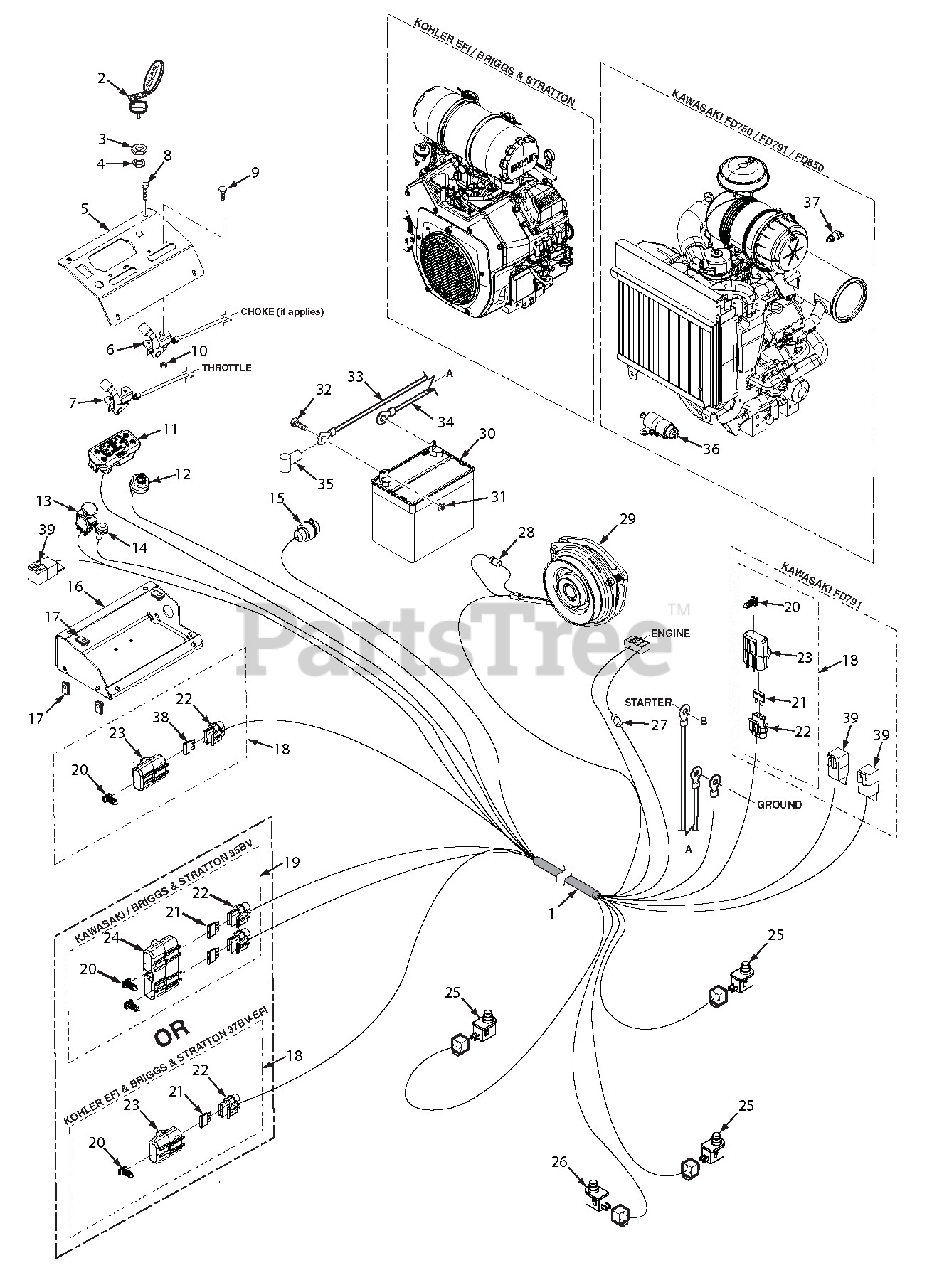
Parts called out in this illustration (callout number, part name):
1	Wire Harness, STTII-BV (Briggs & Stratton)
1	Wire Harness, STTII-BV-EFI (Briggs & Stratton)
1	Wire Harness, STTII-EFI (Kohler)
1	Wire Harness, STTII-KA (Kawasaki)
1	Wire Harness, STTII-FD791 DFI (Kawasaki)
1	Wire Harness, STTII-FD850D DFI (Kawasaki)
2	Key Assy., w/Fob
3	Nut, Hex 5/8-32
4	Lockwasher, 5/8 Internal
5	Instrument Panel w/Decal
6	Choke Cable (FD750 & 35BV)
7	Control Cable, Throttle
7	Control Cable, Throttle (35BV)
8	Capscrew, 1/4-20 x 3/4"
9	Bolt, Carriage 1/4-20 x 1/2"
10	Lock Nut, #10-24
11	Cluster Gauge
12	Key Switch
13	Switch, PTO
14	Indicator Light Assy. (EFI & DFI)
15	Power Plug, 12V
16	Base, Instrument Panel
17	U-Nut, 1/4-20
18	Single Fuse Assy., Excluding Fuse
19	Double Fuse Assy.
20	Clip, Wire
21	Fuse, 20 Amp
22	Fuse Holder
23	Cover, Sealed Single
24	Cover, Sealed Double
25	Switch, N/O
26	Plunger Switch, Single Pole
27	Diode
28	Diode, 600V - 6A
29	Clutch Assembly, GT3.5
29	Clutch Assembly, GT5
30	Battery, 350 CCA
31	Nut, 1/4-20 UNC
32	Bolt, Hex Head 1/4-20 x 1/2"
33	Battery Cable, 44" Red w/Braid (26EFI) - Kohler
33	Battery Cable, 18" Red w/Braid (25KA, 26DFI, 31DFI) - Kawasaki
33	Battery Cable, 50" Red w/Braid (35BV & 37BV-EFI) - Briggs & Stratton
34	Battery Cable, 39" Black (26EFI) - Kohler
34	Battery Cable, 31-1/2" Black (25KA, 26DFI, 31DFI) - Kawasaki
34	Battery Cable, 27" Black (35BV & 37BV-EFI) - Briggs & Stratton
35	Rubber Boot
36	Fuel Pump
37	Sender Unit, Water Temp. (Liquid Cooled Only)
38	Fuse, 5 Amp
39	Relay
